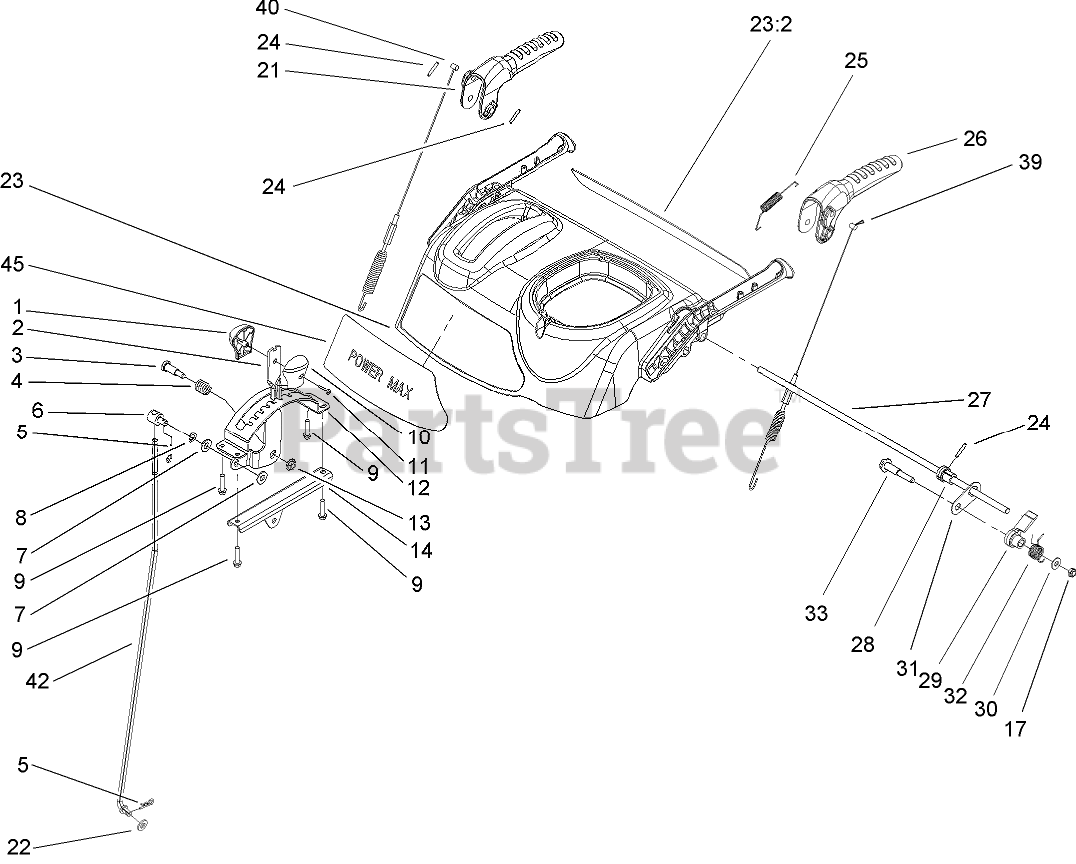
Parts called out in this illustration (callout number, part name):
1	KNOB-SHIFT, RH
2	SELECTOR-SPEED
3	SCREW-SHOULDER
4	SPRING-COMPRESSION
5	PIN-COTTER
6	TRUNNION
7	WASHER-FLAT
8	WASHER-SPRING
9	SCREW-PLASTITE
10	KNOB-SHIFT, LH
11	SCREW-PPH
12	GUIDE-SELECTOR, SPEED
13	NUT-HF
14	MOUNT-SELECTOR, SPEED
17	NUT-LOCK, NI
21	LEVER-AUGER
22	WASHER-FLAT
23	CONTROL PANEL ASM
23:2	DECAL-CONTROL PANEL
24	PIN-SPRING
25	SPRING-TENSION
26	LEVER-TRACTION
27	ROD-LOCKOUT
28	CAM-LOCKOUT
29	LATCH-LOCKOUT
30	WASHER-FLAT
31	LINK-LOCKOUT
32	SPRING-TORSION
33	SCREW-SHOULDER
39	CABLE-TRACTION
40	CABLE-AUGER
42	ROD-SHIFT
45	DECAL-CONTROL PANEL, TSS
